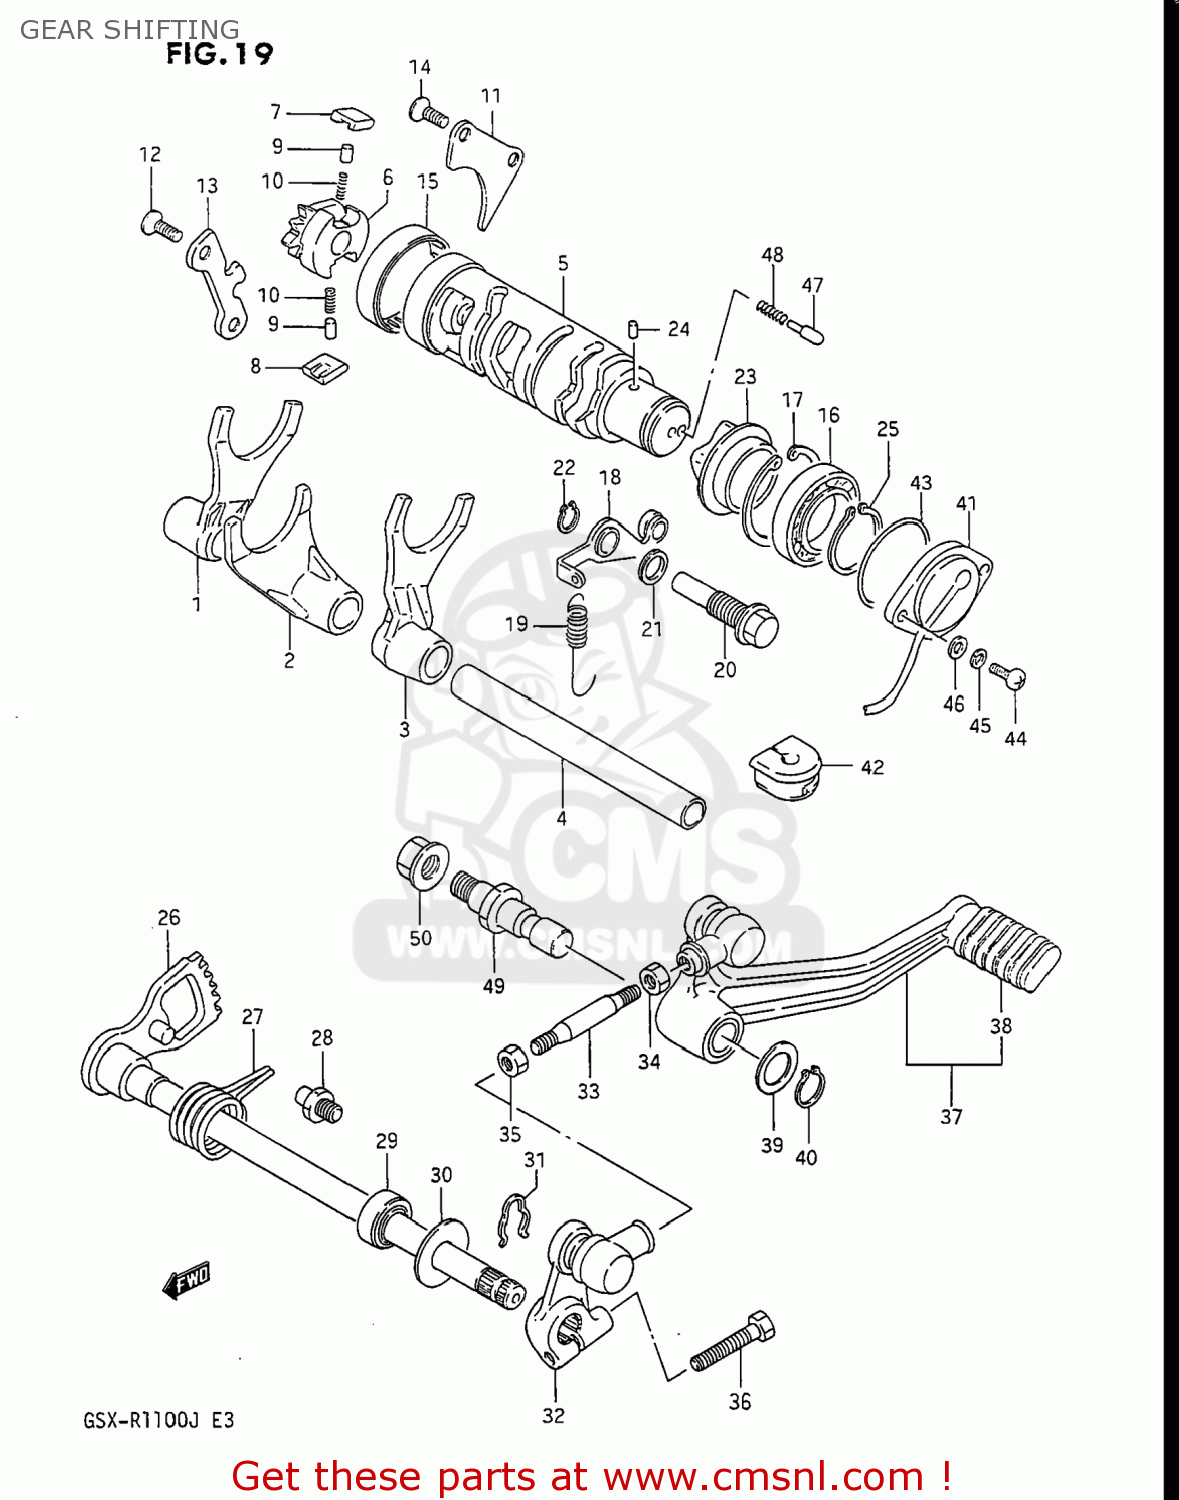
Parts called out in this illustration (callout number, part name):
1	FORK,GEAR SHIFT NO.1
2	FORK,GEAR SHIFT NO.2
3	FORK,GEAR SHIFT NO.3
4	SHAFT,GEAR SHIFT FORK(L:128)
5	CAM,GEAR SHIFT
6	GEAR,GEARSHIFT CAM DRIVE
7	PAWL,GEAR SHIFT NO.1
8	PAWL,GEAR SHIFT NO.2
9	PIN(5X8)
10	SPRING
11	LIFTER,GEAR SHIFT PAWL
12	SCREW
13	GUIDE,GEAR SHIFT CAM
14	SCREW
15	BEARING(43X49X12)
16	BALL BEARING
17	CIRCLIP,42MM
18	STOPPER,GEAR SHIFT CAM
19	SPRING
20	SHAFT,GEAR SHIFT CAM STOPPER
21	GASKET(10X14X3.6) (NAS)
22	CIRCLIP
23	PLATE,STOPPER
24	PIN 4X6
25	CIRCLIP,25MM
26	SHAFT,GEAR SHIFT
27	SPRING
28	STOPPER,GEAR SHIFT CAM
29	OIL SEAL
30	WASHER (12.5X27X1.6)
31	SPRING,RETAINER
32	ARM,GEAR SHIFT
33	ROD,GEAR SHIFT LINK
34	NUT
35	NUT 6MM
36	BOLT
37	LEVER ASSY,GEAR SHIFT
38	RUBBER,BRAKE PEDAL
39	WASHER(12.5X20X1)
40	CIRCLIP
41	TERMINAL BASE ASSY,NEUTRAL
42	GROMMET,LEAD WIRE
43	O RING(D:2.4,ID:36.5)
44	SCREW(5X14)
45	LOCK WASHER
46	WASHER
47	PIN(5X15.5)
48	SPRING
49	SHAFT,GEAR SHIFT LEVER
50	NUT
